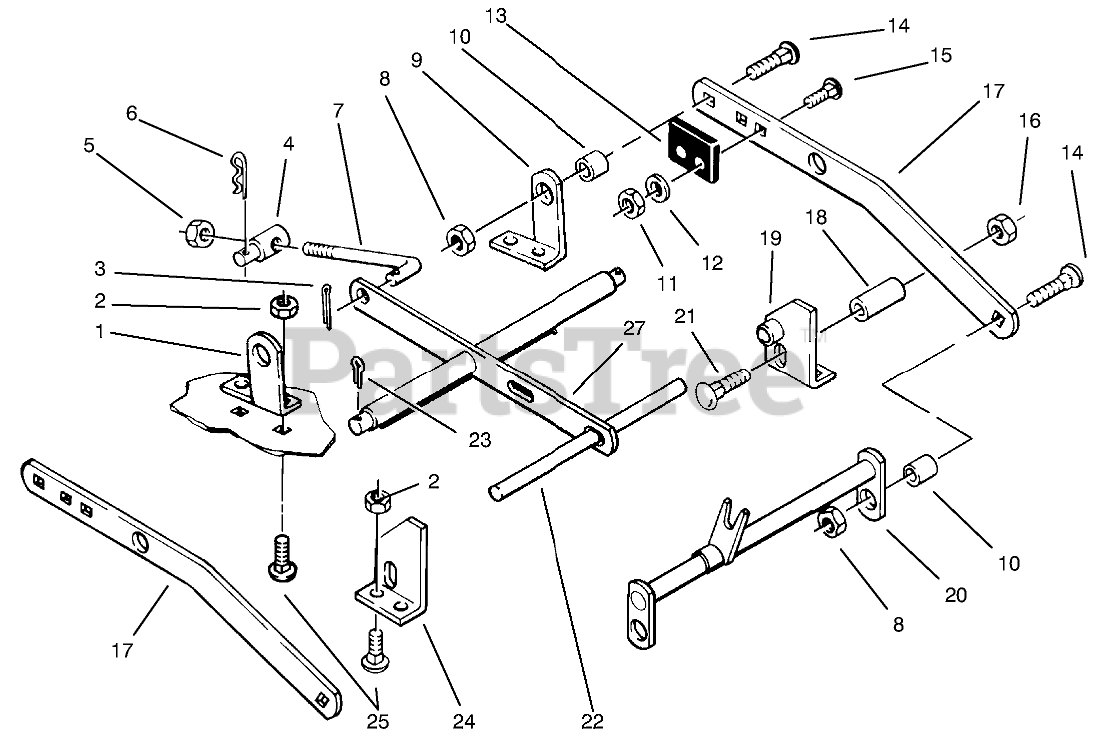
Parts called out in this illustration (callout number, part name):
1	RH BRKT-DECK REAR (RED)
2	NUT-LOCK, NI
3	PIN-COTTER
4	TRUNNION-LIFT
5	NUT-LOCK, NI
6	Hairpin
7	ROD-LEVEL ADJUST
8	LOCKNUT-FLANGE
9	LH BRKT-DECK REAR (RED)
10	SPACER
11	NUT-LOCK, NI
12	WASHER-FLAT
13	BUMPER
14	BOLT-CARR
15	SCREW-CARR
16	NUT-LOCK, NI
17	BAR DRAFT (RED)
19	WA BRACKET FT L (RED)
20	WA HITCH (RED)
21	BOLT-CARR
22	SHAFT FRONT (RED)
23	PIN-COTTER
24	WA BRACKET FT R (RED)
25	BOLT-CARR
27	LEVELER WA (RED)
